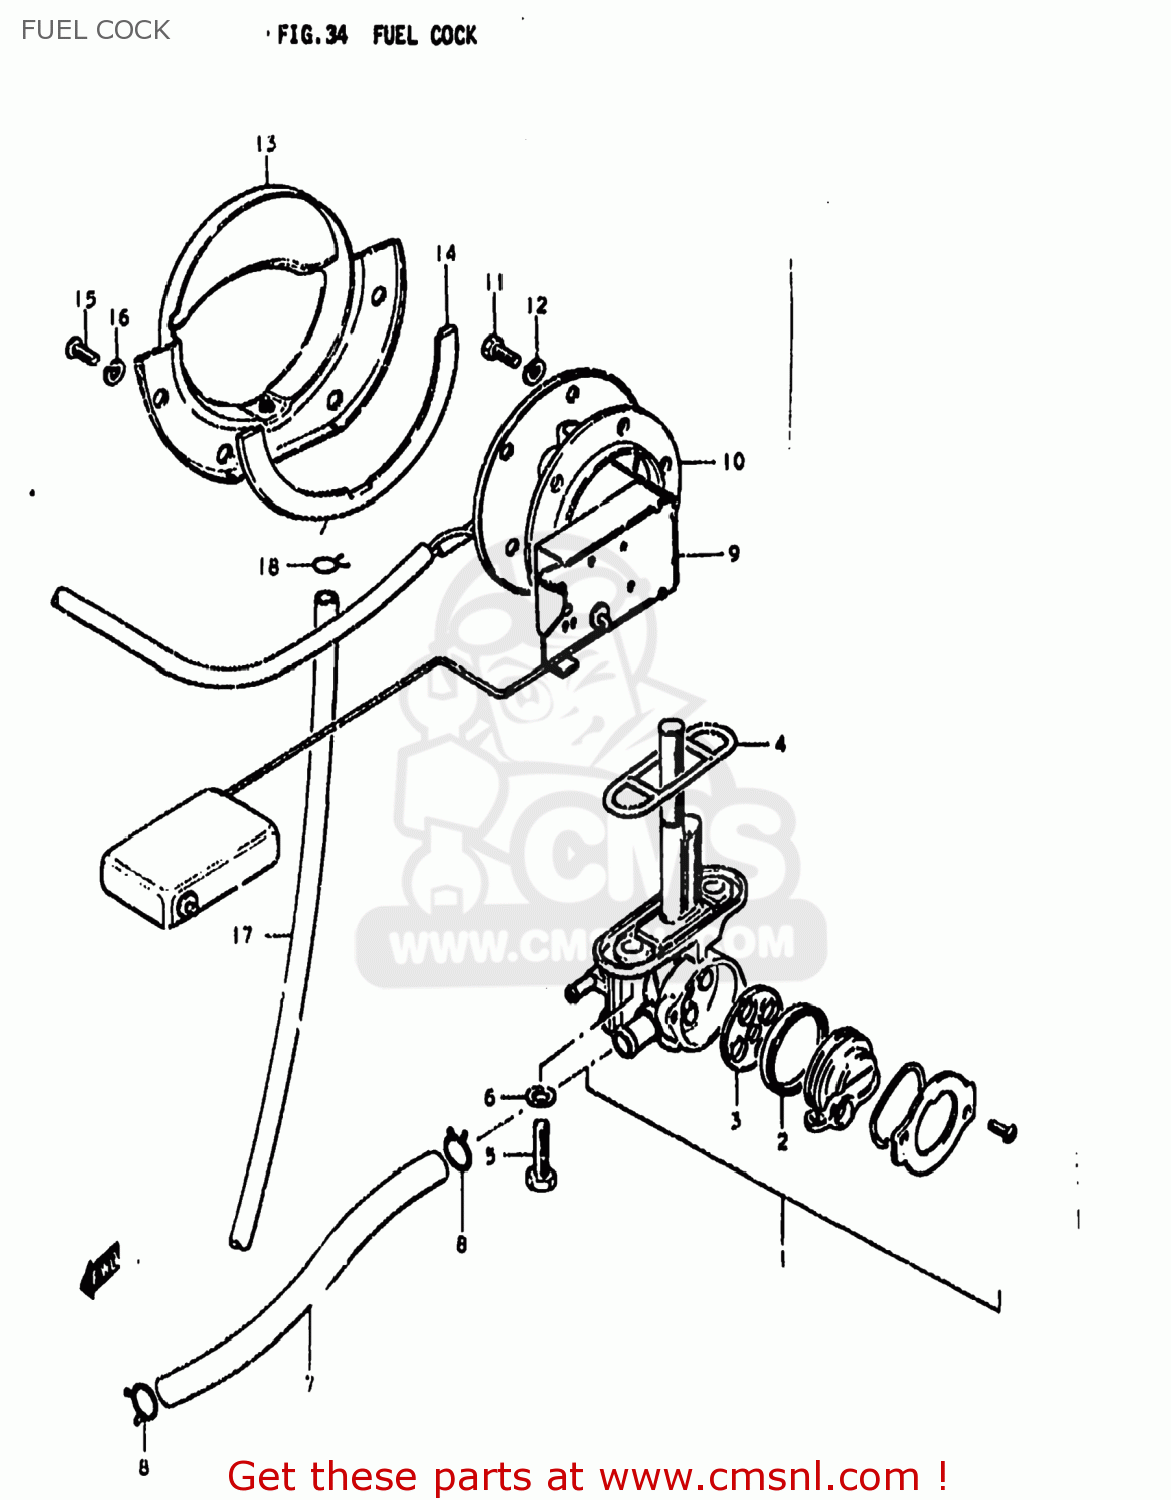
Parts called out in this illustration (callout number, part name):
1	COCK ASSY,FUEL
2	V SEAL,FUEL COCK
3	GASKET (NAS)
4	GASKET, FUEL COCK (NAS)
5	BOLT(6X20)
6	GASKET
7	HOSE
8	CLIP
9	GAUGE ASSEMBLY,FUEL LEVEL
10	GASKET,FUEL LEVEL GAUGE (NAS)
11	BOLT 5X16
12	LOCK WASHER
13	PLATE,FUEL DRAIN
14	GASKET,FUEL DRAIN PLATE (NAS)
15	SCREW
16	LOCK WASHER
17	HOSE
18	CLIP
